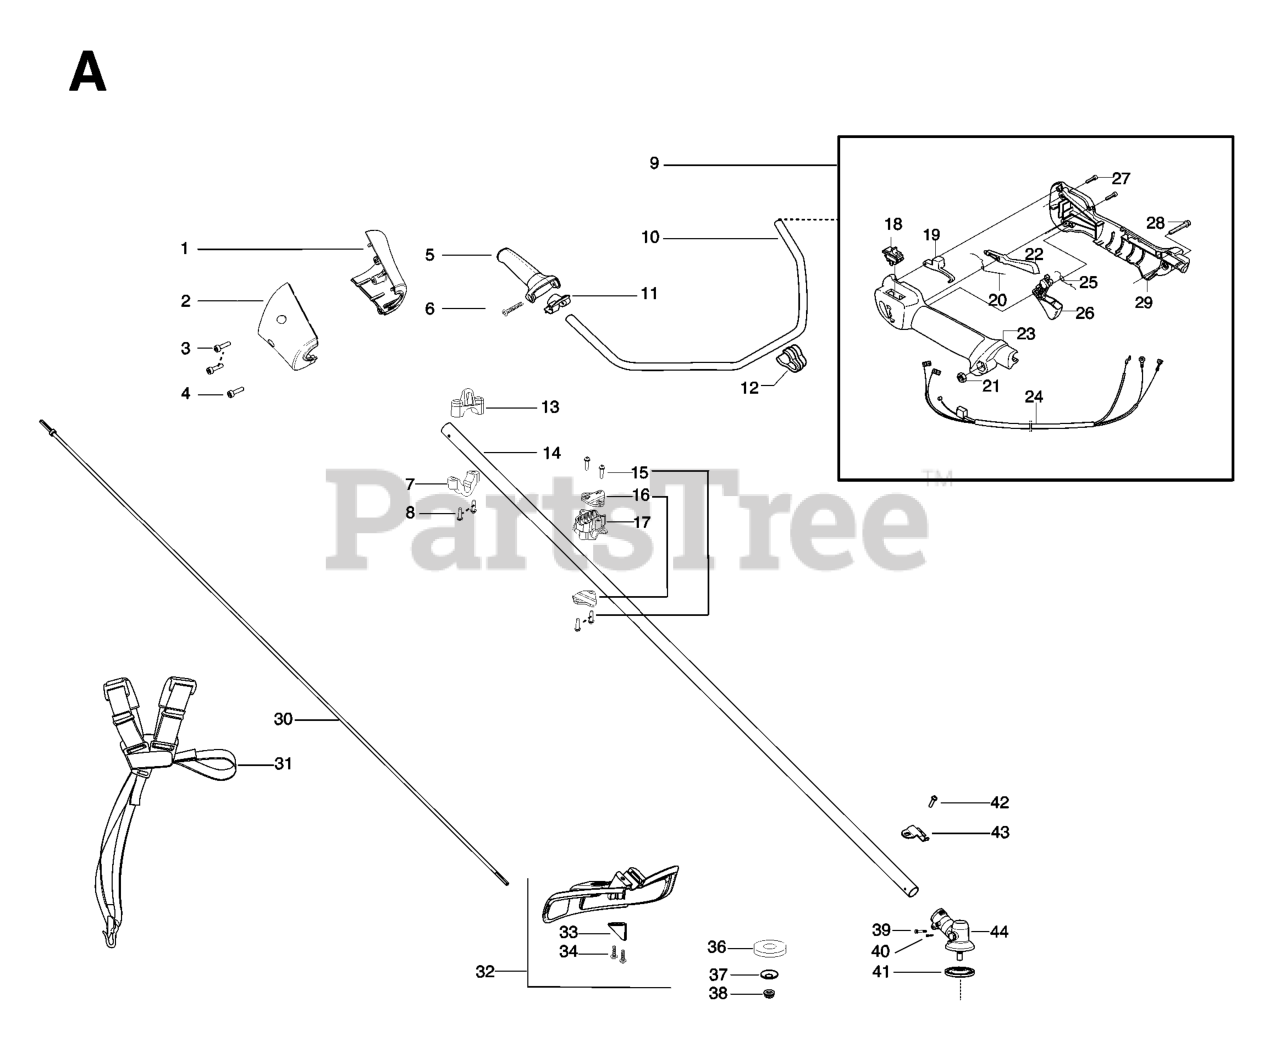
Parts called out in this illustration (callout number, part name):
1	NOSE CONE BH LEFT
2	NOSE CONE BH RIGHT
4	SCREW M4 X 1.75 PT 16MM
7	CLAMP HARNESS LOWER
9	ASSY THROTTLE HOUSING
13	CLAMP HARNESS UPPER
14	KIT DRIVESHAFT SST
16	CLAMP BRACKET
18	KIT SWITCH
19	LOCKOUT STARTER THROTTLE
22	THROTTLE LOCK
24	THROTTLE CABLE
26	THROTTLE TRIGGER
28	SCREW
30	FLEXSHAFT 57"
31	Harness - Diagonal with sign
32	KIT COBI SHIELD
33	Limiter - Line
36	SUPPORTING CUP
37	SUPPORT FLANGE
38	GEARHEAD NUT - BRUSHCUTTER
39	SCREW - CARB. ADAPTOR
41	ASSY DUST CUP
42	SCREW 1/4-20 X 7/8 (TAP
43	BRACKET SHIELD STRAIGHT SHAFT
44	ASSY GEARBOX
